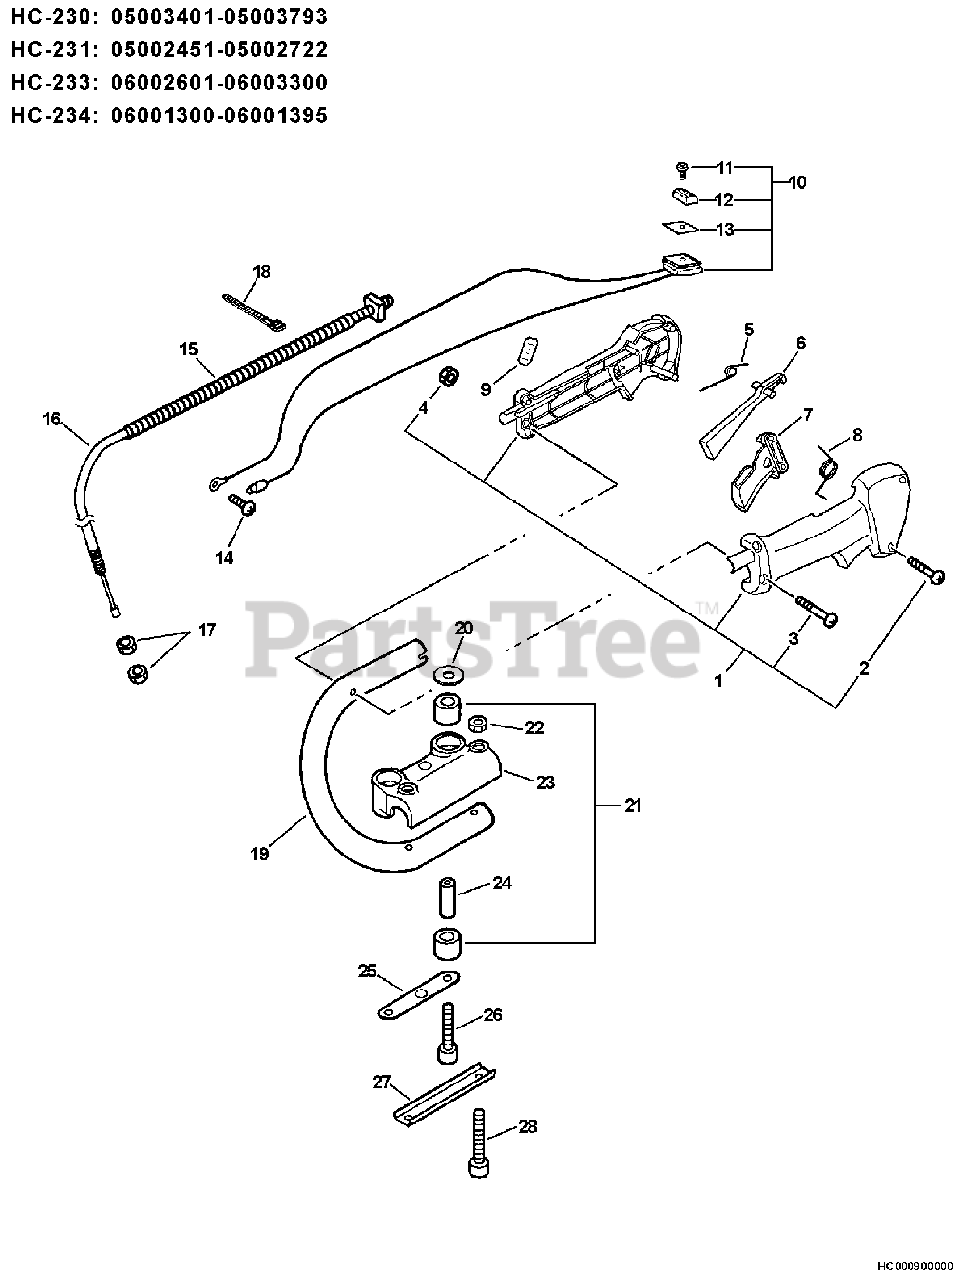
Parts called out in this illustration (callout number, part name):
1	FRONT HANDLE GRIP ASSY
2	SCREW 4×16
3	SCREW 5×30
4	NUT M5
5	SPRING, TORSION
6	LOCKOUT, THROTTLE
7	TRIGGER, THROTTLE
8	SPRING, TORSION
10	SWITCH, ON-OFF
11	SCREW 3×10
12	KNOB, SWITCH - ORANGE
13	LABEL, SWITCH
14	SCREW 5×10
15	TUBE, FLEXIBLE
16	CABLE, THROTTLE
18	STRAP, TIE
19	HANDLE, REAR
20	WASHER 5.5×18×1
22	NUT M5
23	BRACKET, HANDLE - UPPER
24	SPACER
25	PLATE, EYE
26	BOLT 5×45
28	BOLT M5×35
